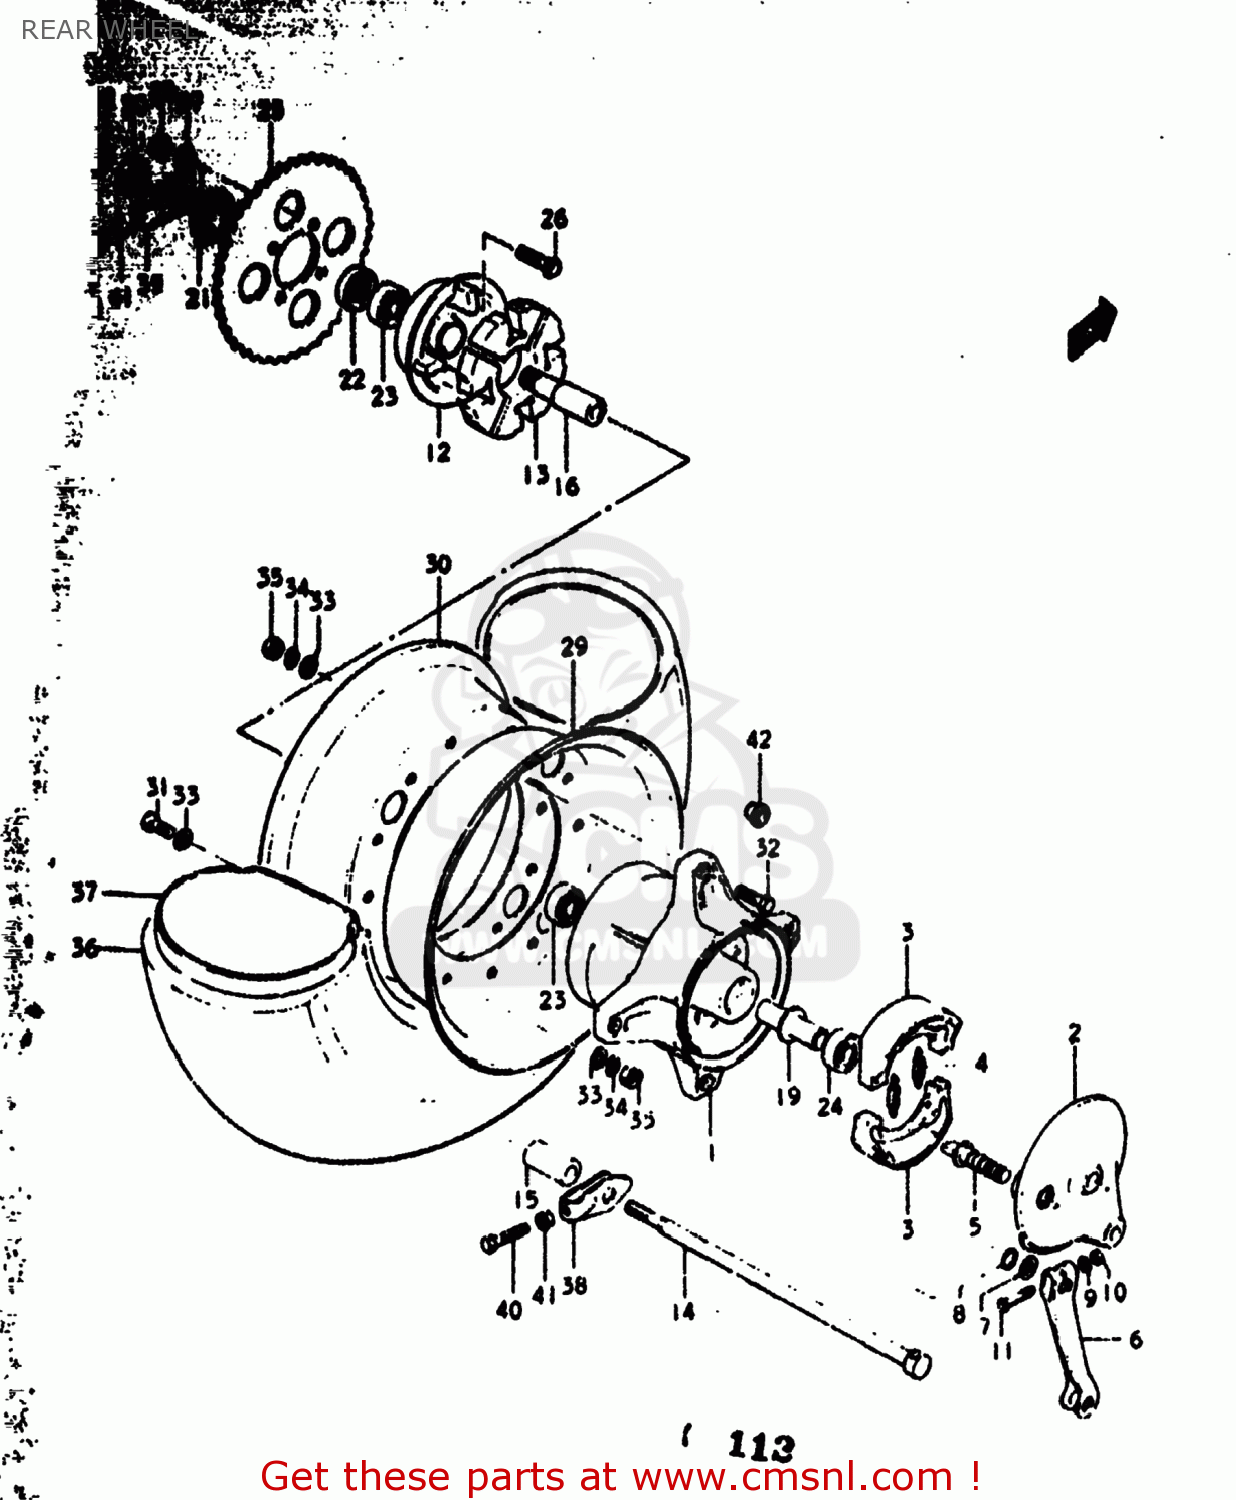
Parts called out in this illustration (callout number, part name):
1	HUB,REAR
2	PANEL,REAR HUB
3	SHOE,BRAKE
4	SPRING(L:34)
5	CAM,FR BRAKE
6	LEVER,RR BRAKE CAM
7	WASHER(12.5X20X1)
8	O RING(D:2.5,ID:11.4)
9	WASHER
10	NUT
11	BOLT
12	DRUM,REAR SPROCKET MOUNT
13	CUSHION,REAR DRUM
14	AXLE,RR
15	SPACER (12.2X22X37.7)
16	SHAFT,RR SPROCKET DRUM
17	NUT
18	COTTER PIN
19	SPACER,REAR HUB BEARING
20	NUT
21	SPACER,REAR SPROCKET DRUM
22	SEAL OIL(25X40X6)
23	BEARING, LH
24	BEARING
25	SPROCKET,RR
26	BOLT(8X33.5)
27	WASHER
28	NUT
29	RIM,WHEEL,RIGHT
30	RIM,WHEEL,OUTER
31	BOLT
32	BOLT
33	WASHER
34	LOCK WASHER
35	NUT
36	TIRE. (BRIDGESTONE)
37	TUBE,INNER
38	ADJUSTER,CHAIN
39	ADJUSTER,CHAIN
40	BOLT(6X38)
41	NUT
42	BUSHING
